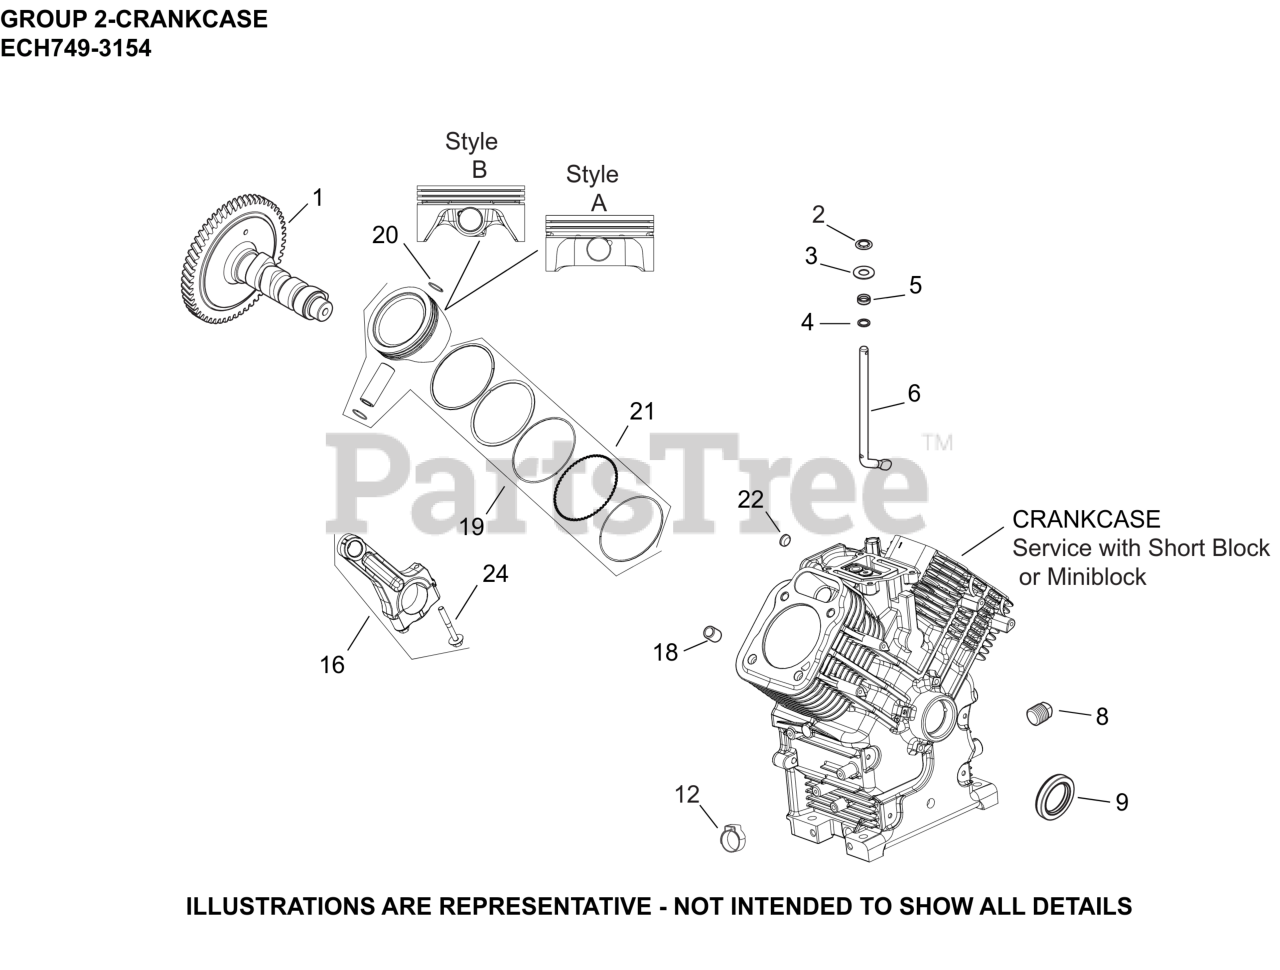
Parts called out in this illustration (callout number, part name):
1	KIT, CAMSHAFT
2	RETAINER, RING
3	WASHER, FLAT 9 MM
4	WASHER, FLAT 11/32"
5	SEAL, GOVERNOR CROSS SHAFT
6	SHAFT, GOVERNOR CROSS
8	PLUG, HD PIPE 3/8"
9	SEAL, OIL (HELIX LIP)
16	ROD, ASSEMBLY CONNECTING
18	PIN, LOCATING
19	KIT,PSTN/RNG STYLE B(STD)
19	KIT,PSTN/RNG STYLE B(.08)
19	KIT,PSTN/RNG STYLE B(.25)
19	KIT,PSTN/RNG STYLE B(.50)
20	RETAINER, PISTON PIN
21	RING SET(STD)STYLE B-1.2mm Tp RING THICK
21	RING SET(.08)STYLE B-1.2mm RING THICK
21	RING SET(.25)STYLE B-1.2mm Tp RING THICK
21	RING SET(.50)STYLE B-1.2mm Tp RING THICK
22	PLUG, CUP
24	KIT, ROD BOLTS-(#25086677S)
